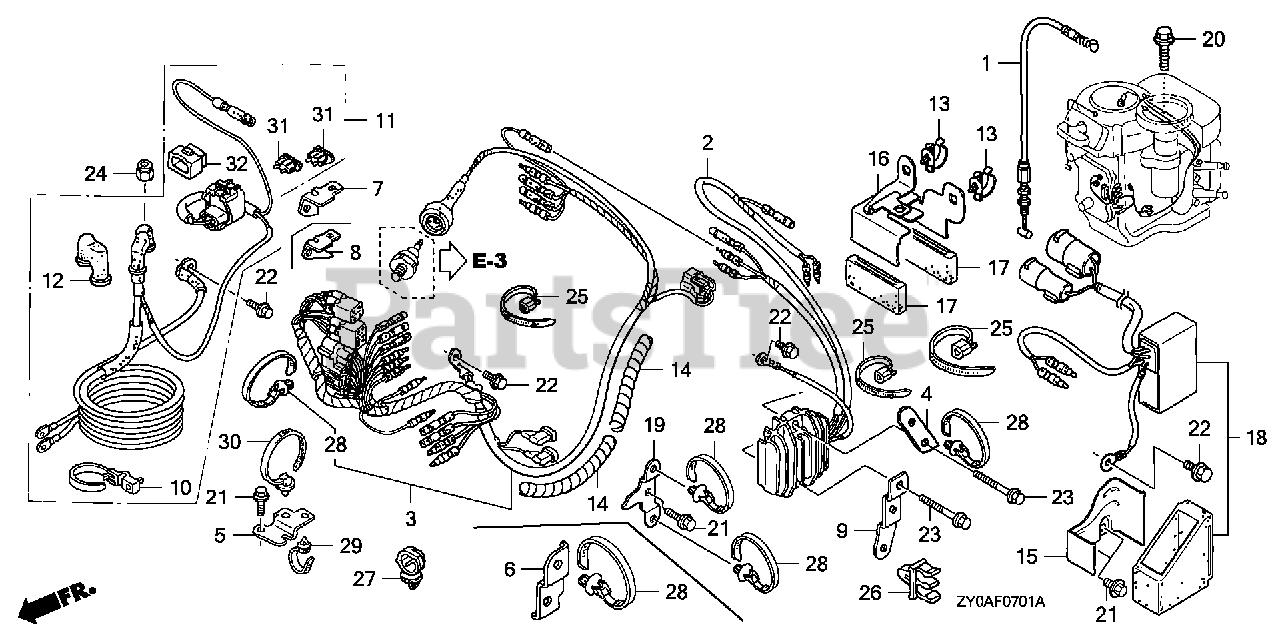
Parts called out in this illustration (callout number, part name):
1	CABLE, NEUTRAL STARTING
2	RECTIFIER ASSY., REGULATOR
3	WIRE HARNESS ASSY. (REMOTE CONTROL)(PT)
4	BRACKET, CLIP F
5	BRACKET, STARTER CABLE
8	BRACKET, FUSE CASE (PT)
9	BRACKET, E-CLIP
10	BAND, WIRE
11	CABLE ASSY., STARTER (PT)
12	COVER, MAGNETIC SWITCH TERMINAL
13	CLAMP, WIRE
14	TUBE, SPIRAL A
15	BRACKET, RELAY (PT)
16	BRACKET, CONNECTOR A
17	GROMMET, CONNECTOR
18	RELAY ASSY., POWER TILT
19	BRACKET, HARNESS CLIP
20	BOLT, FLANGE (6X20)
21	BOLT, FLANGE (6X14) (CT200)
22	BOLT, FLANGE (6X12)
23	BOLT, FLANGE (6X26) (CT200)
24	NUT, LOCK (6MM)
25	TIE, CABLE
26	CLIP, FUEL TUBE
28	CLIP, HARNESS BAND (151.5MM) (NATURAL)
29	BAND, WIRE HARNESS (123.5MM) (BLUE)
30	BAND, WIRE HARNESS (93.5MM) (WHITE)
31	FUSE, BLADE (20A)
32	COVER ASSY., FUSE (20A)
